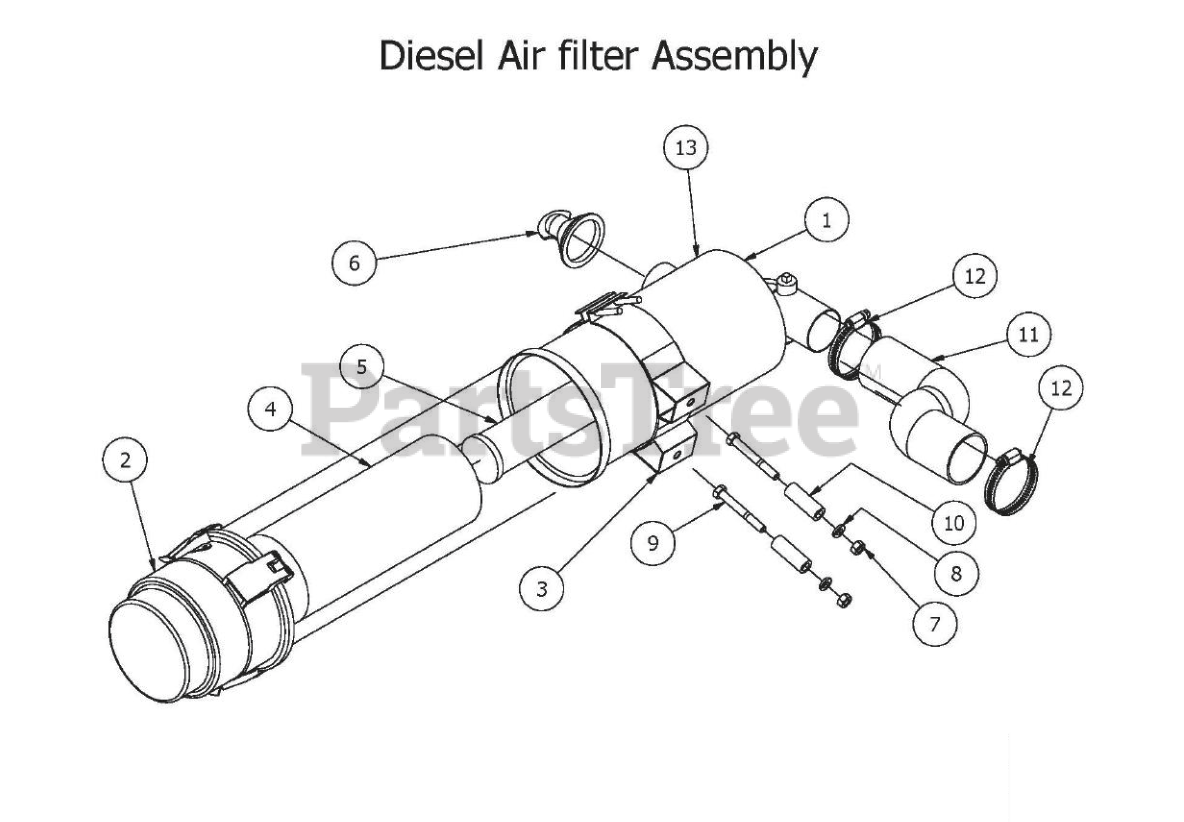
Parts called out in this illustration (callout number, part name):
1	Canister for All Diesel Models
2	Enginaire Air canister cap
3	Mounting Bracket For Diesel Air Filter
4	Diesel Air Filter- Outer
5	Diesel Air Filter- Inner
6	Debris Plug-Enginaire Filter
8	5/16" Lock Washer
9	5/16" x 2 1/2" Bolt
10	.378 x .625x 1.750 Spacer Zinc
11	Air Intake Hose-Diesel Air Filter Canister
12	2-1/2" Hose Clamp
13	Enginaire Canister VLR-Complete Assembly
